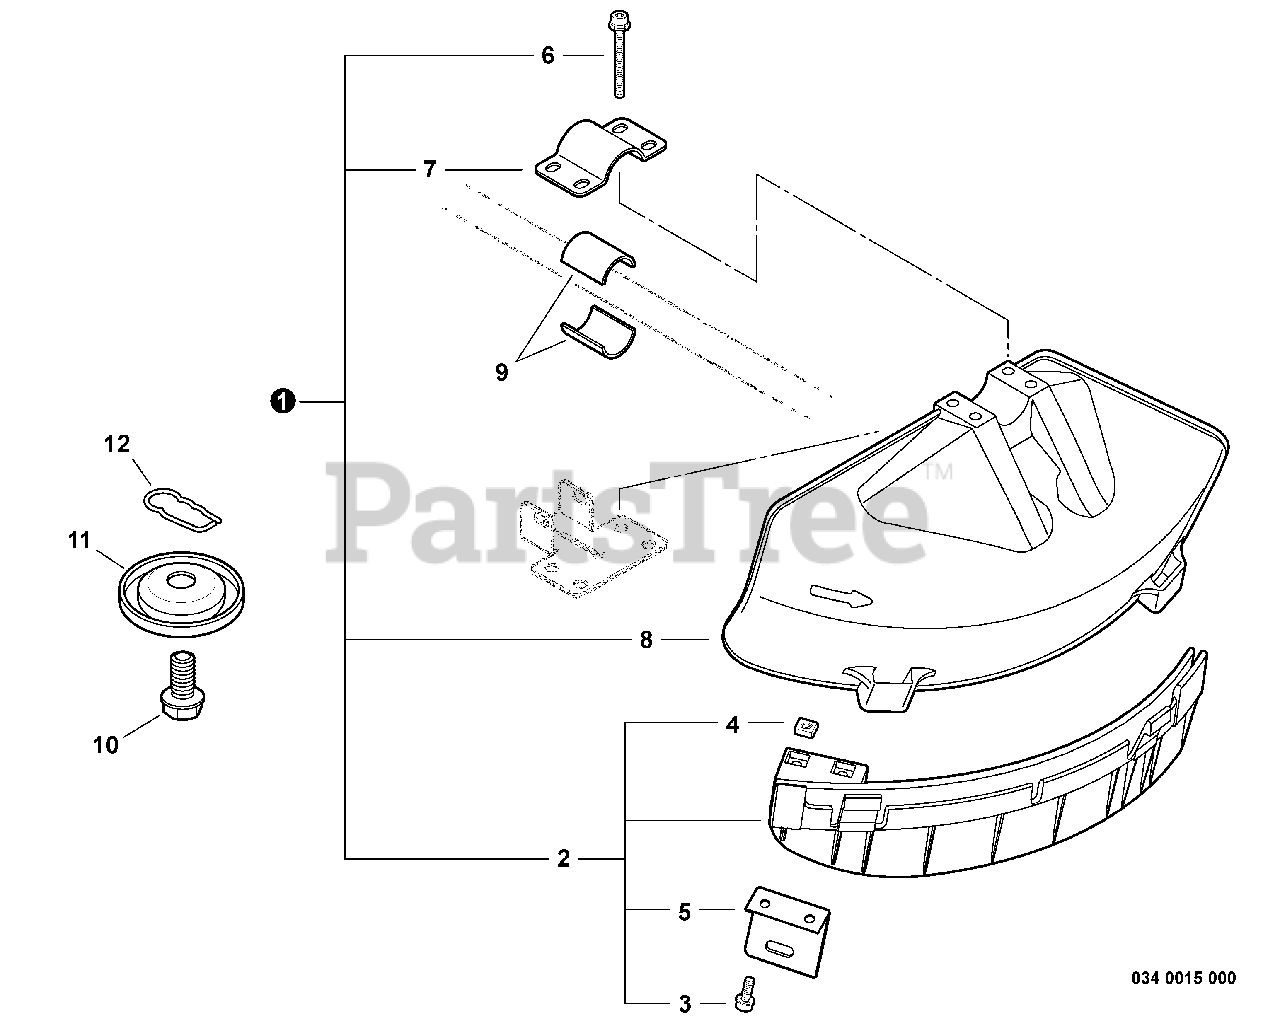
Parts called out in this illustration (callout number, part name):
1	DEBRIS SHIELD KIT
2	DEBRIS SHIELD EXTENSION ASSY
3	BOLT M5×16
6	BOLT M5×45
7	CLAMP, UPPER
8	SHIELD, DEBRIS PLASTIC
9	SPACER 26
11	GUARD, BOLT
12	CLIP, BLADE
